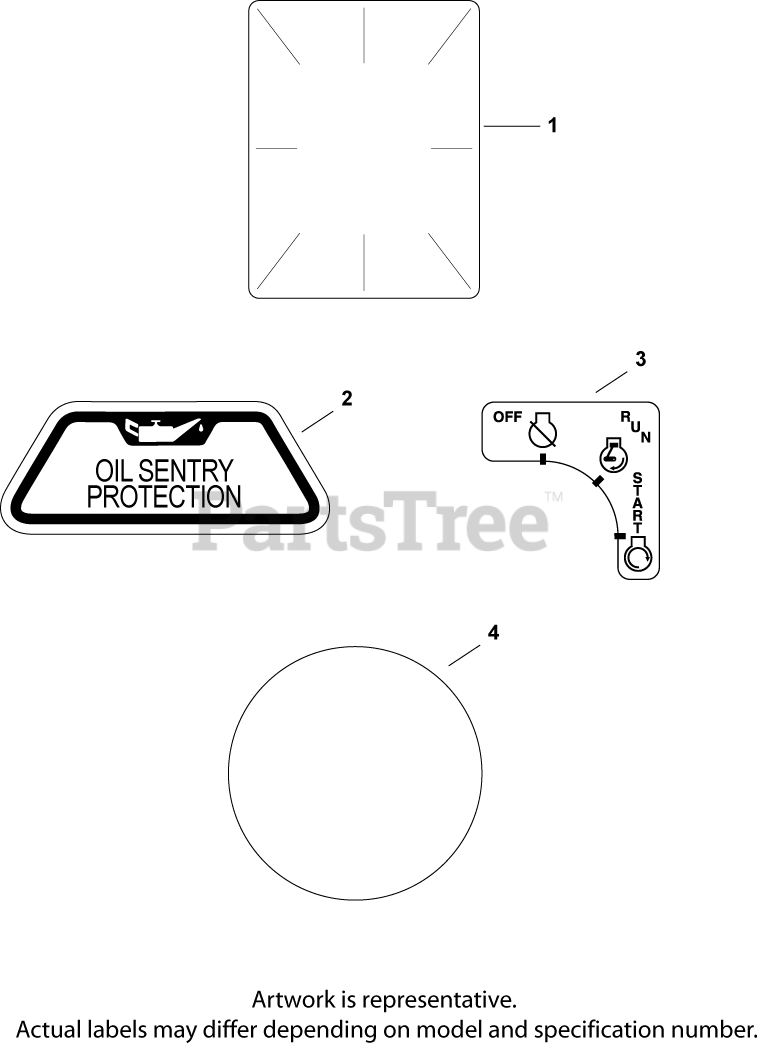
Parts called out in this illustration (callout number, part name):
1	DECAL, CLEAR LAMINATE USE 25 113 70-S
2	DECAL, OIL SENTRY - (#DSC)
3	DECAL, KEY SWITCH
4	DECAL, GRASS SCREEN USE 24 113 499-S
